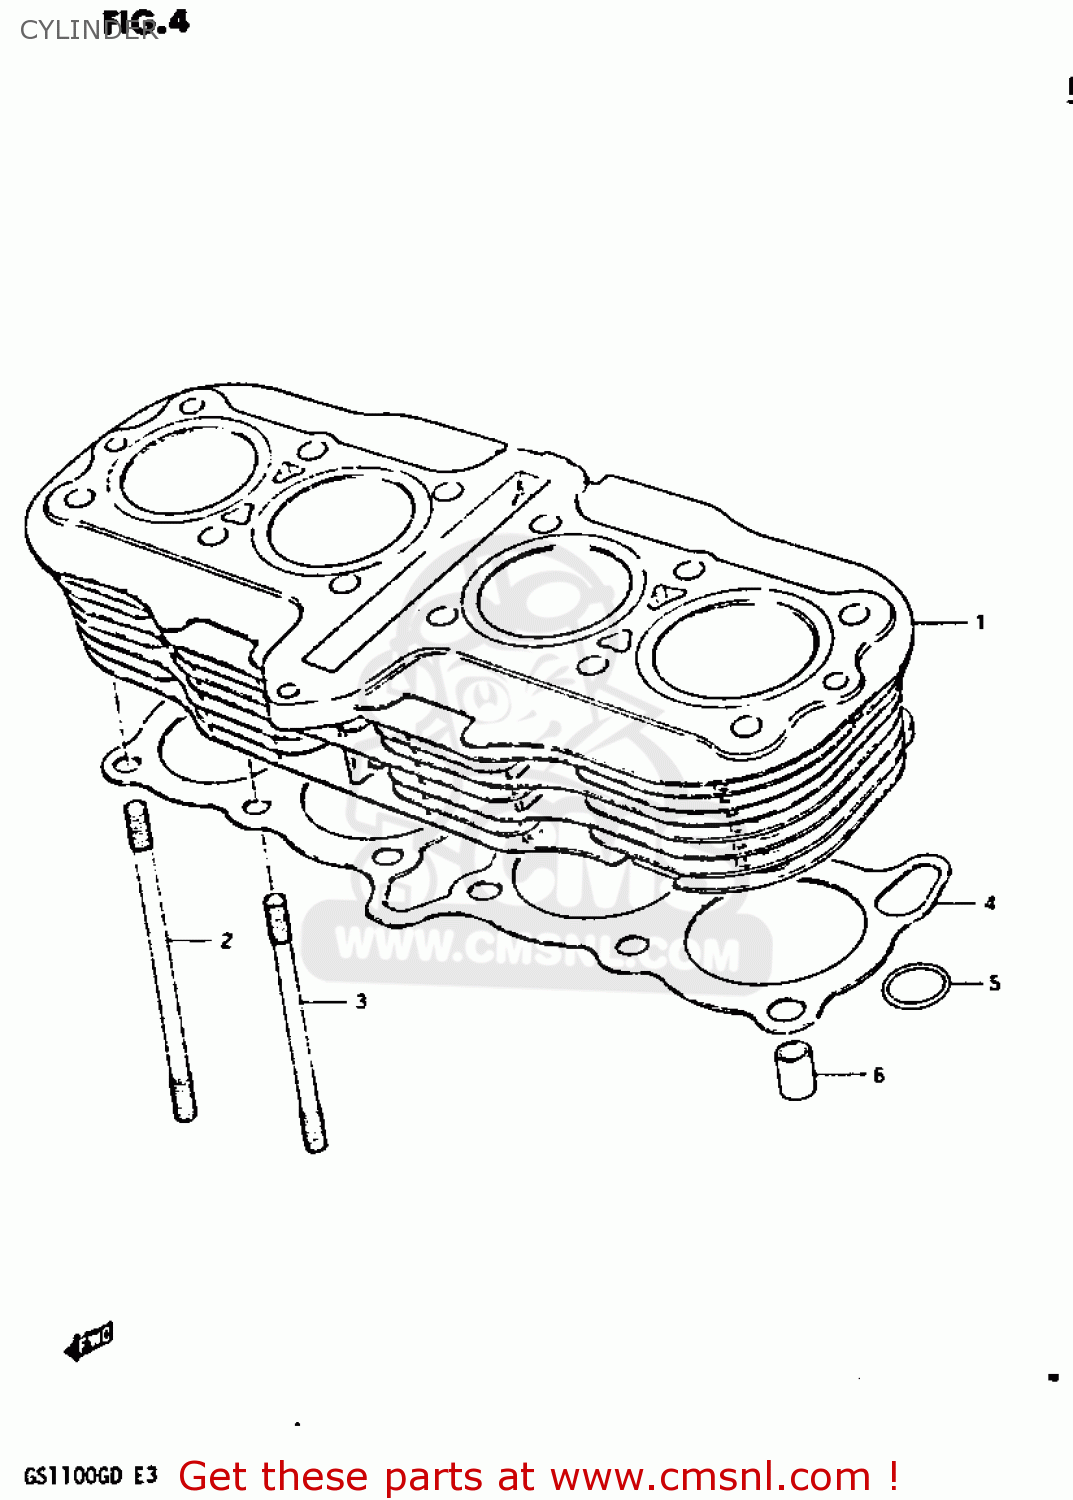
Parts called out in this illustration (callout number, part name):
1	CYLINDER
2	BOLT,STUD
3	BOLT,STUD
4	GASKET,CYLINDER (NAS)
5	O-RING
6	PIN
